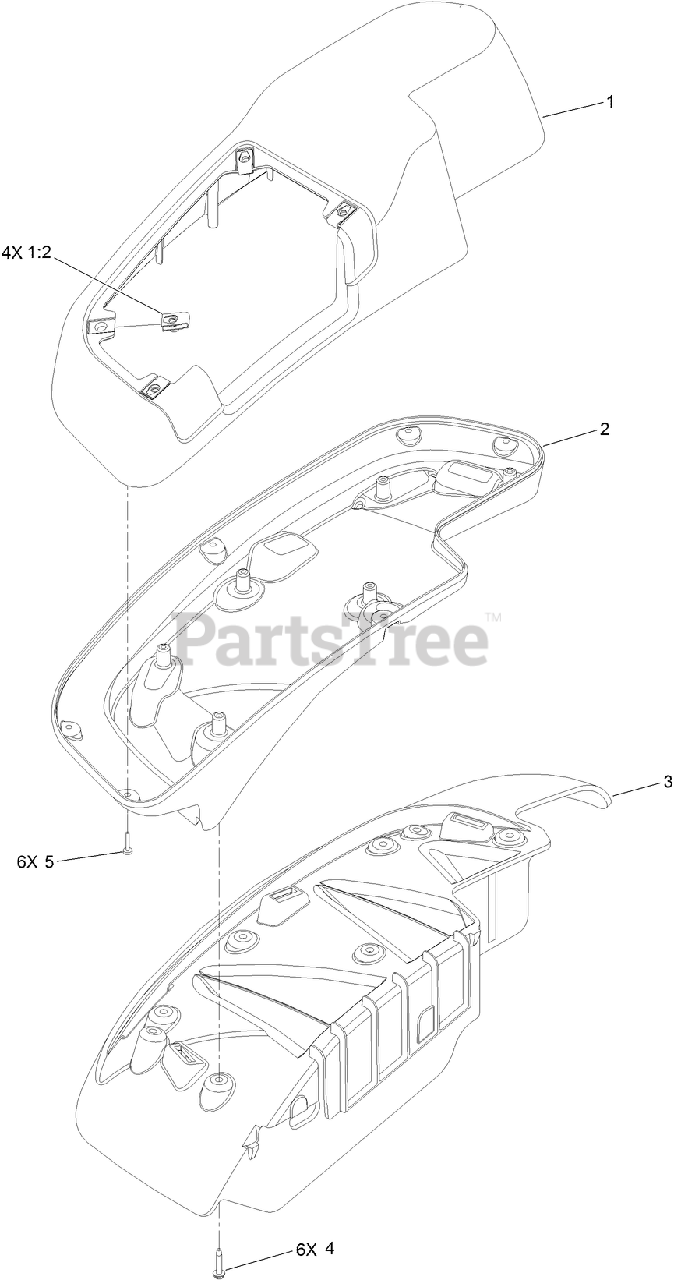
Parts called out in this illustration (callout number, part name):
1	RH CONSOLE TOP ASM
2	CONSOLE-NARROW, RH
3	FENDER-NARROW, RH
4	SCREW-THREAD FORMING
